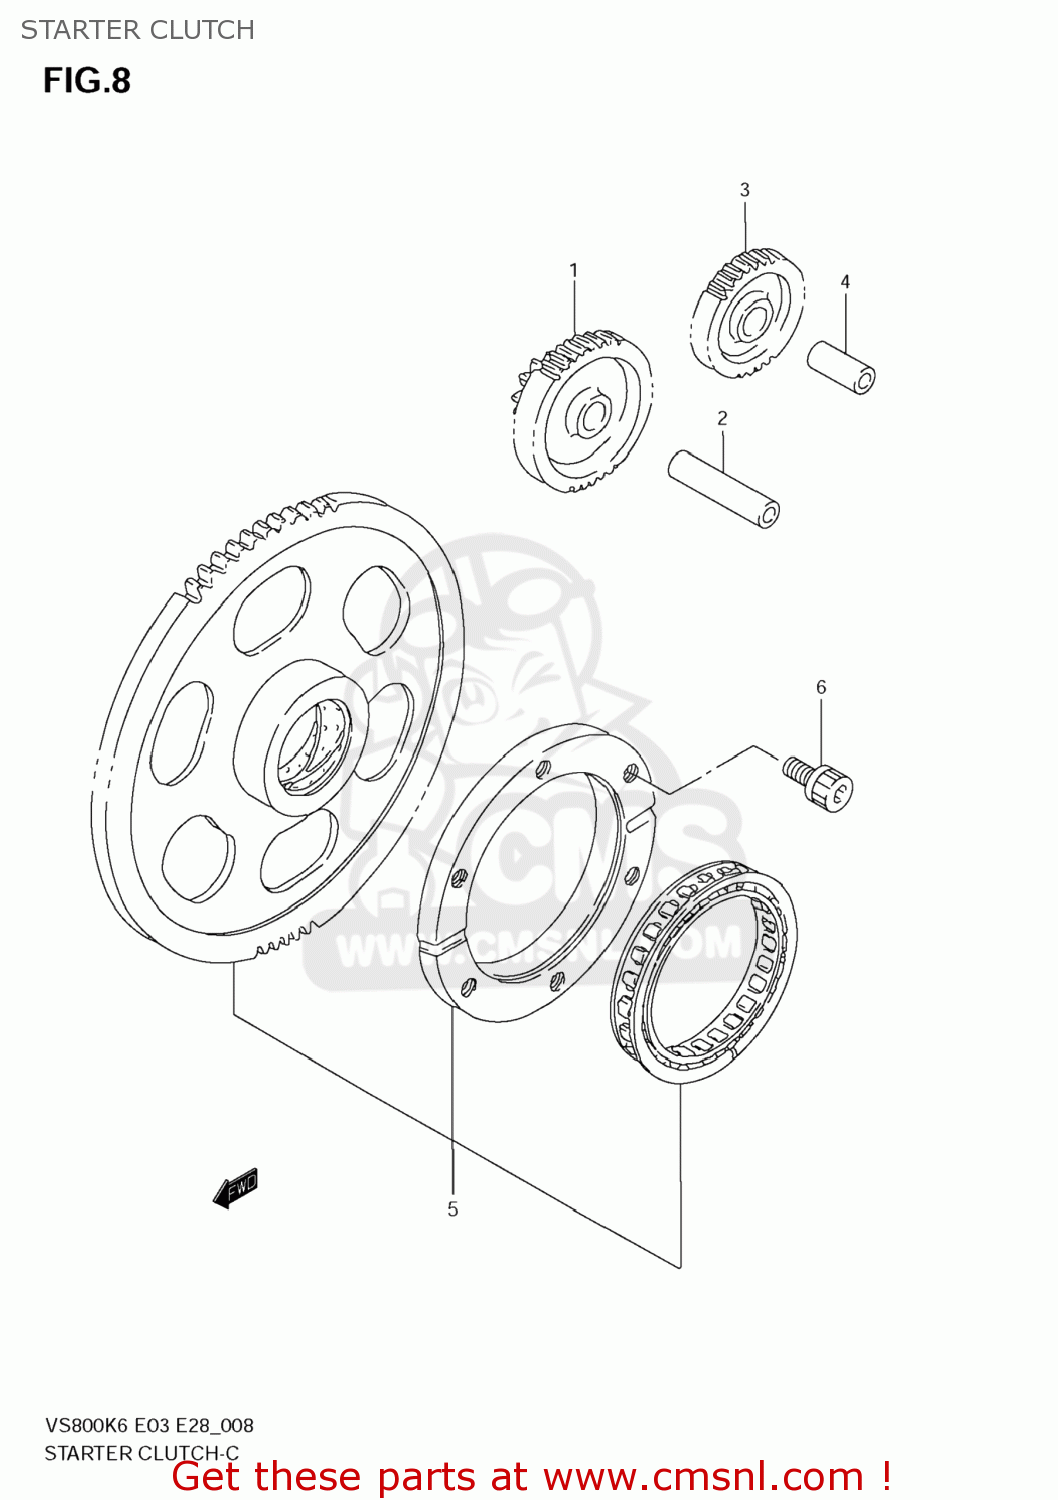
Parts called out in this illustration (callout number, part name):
1	GEAR,STARTER IDLE NO.1
2	PIN,10X43
3	GEAR,STARTER IDLE NO.2
4	PIN
5	CLUTCH SET,STARTER
6	BOLT(8X16)
